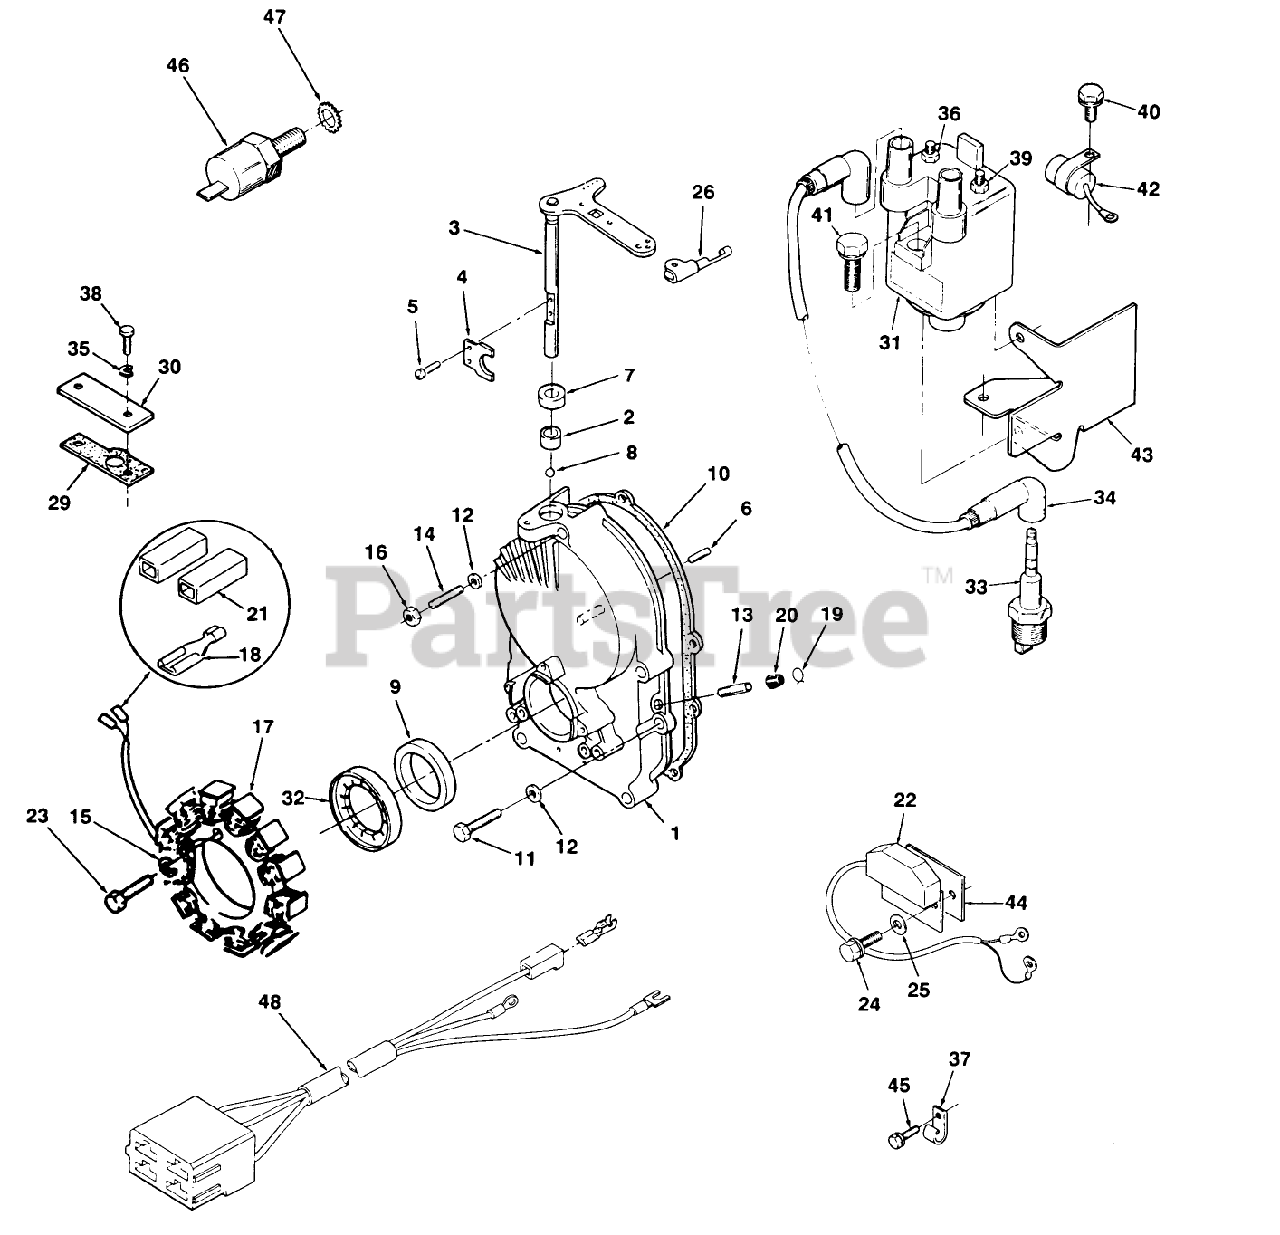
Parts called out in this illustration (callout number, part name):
5	SCREW-PAN HD
6	PIN-DOWEL
12	WASHER
13	TUBE-PORT, VACUUM
14	STUD-GEAR COVER
16	NUT-GEAR COVER
18	TERMINAL
20	CAP-FUEL OUTLET
21	BODY-TERM. CONNECTOR KIT
25	WASHER-LOCK
30	PLATE-COVER
31	COIL-BATTERY IGNITION
32	ROTOR-IGNITION
33	SPARK PLUG
35	WASHER-FLAT
37	CLIP-WIRE
38	SCREW - CAP HEX HEAD
40	HEX HD CAPSCREW
42	CONDENSER
43	BRACKET - COIL MTG
48	WIRE HARNESS
